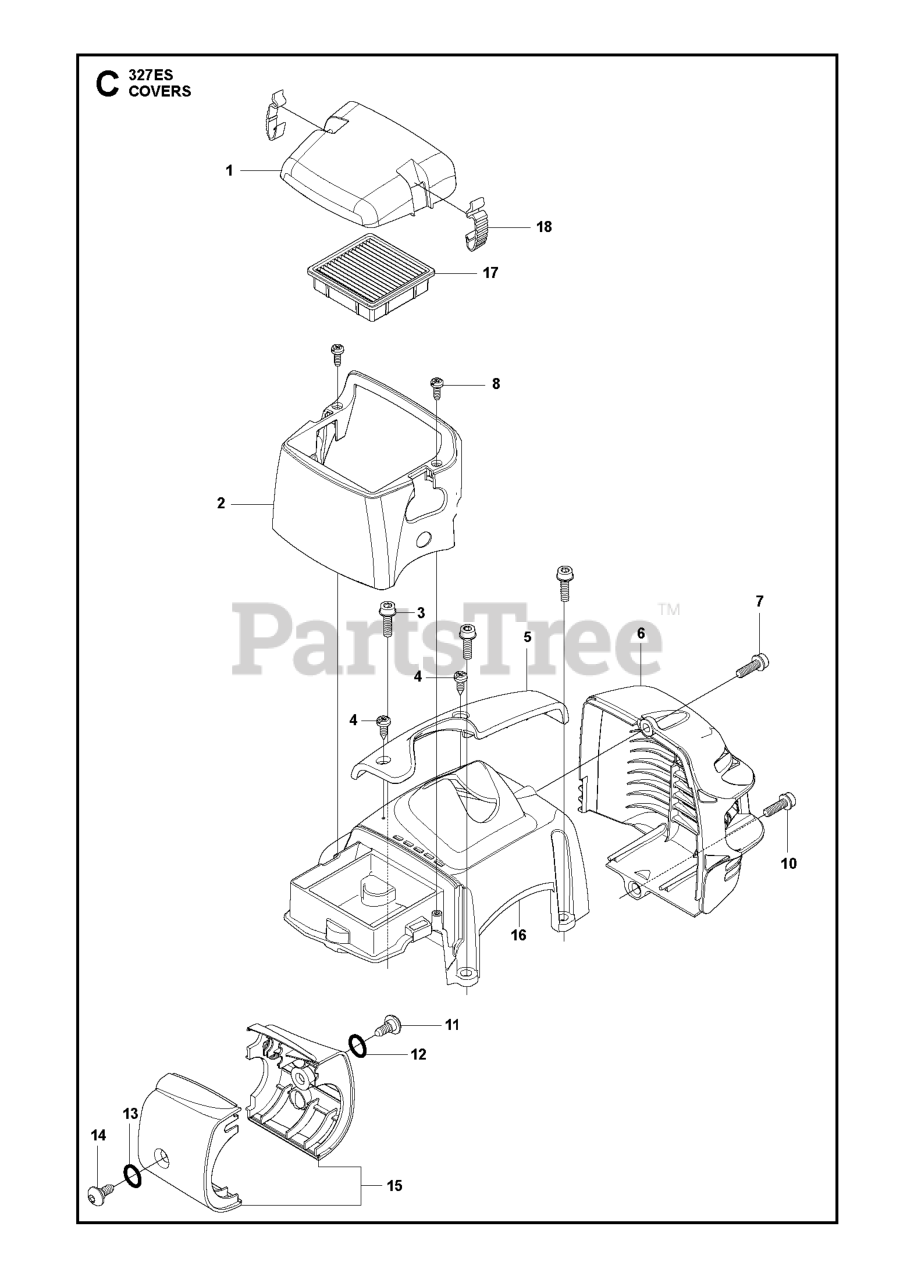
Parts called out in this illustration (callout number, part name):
1	FILTER COVER
3	SCREW
5	ARM PROTECTION
6	RP HEAT PROTECTOR
7	SCREW
11	SCREW MT5X11
12	O-RING 8X1.6
13	O-RING 8X1.6
14	SCREW MT5X11
16	CYLINDER COVER ASSY
